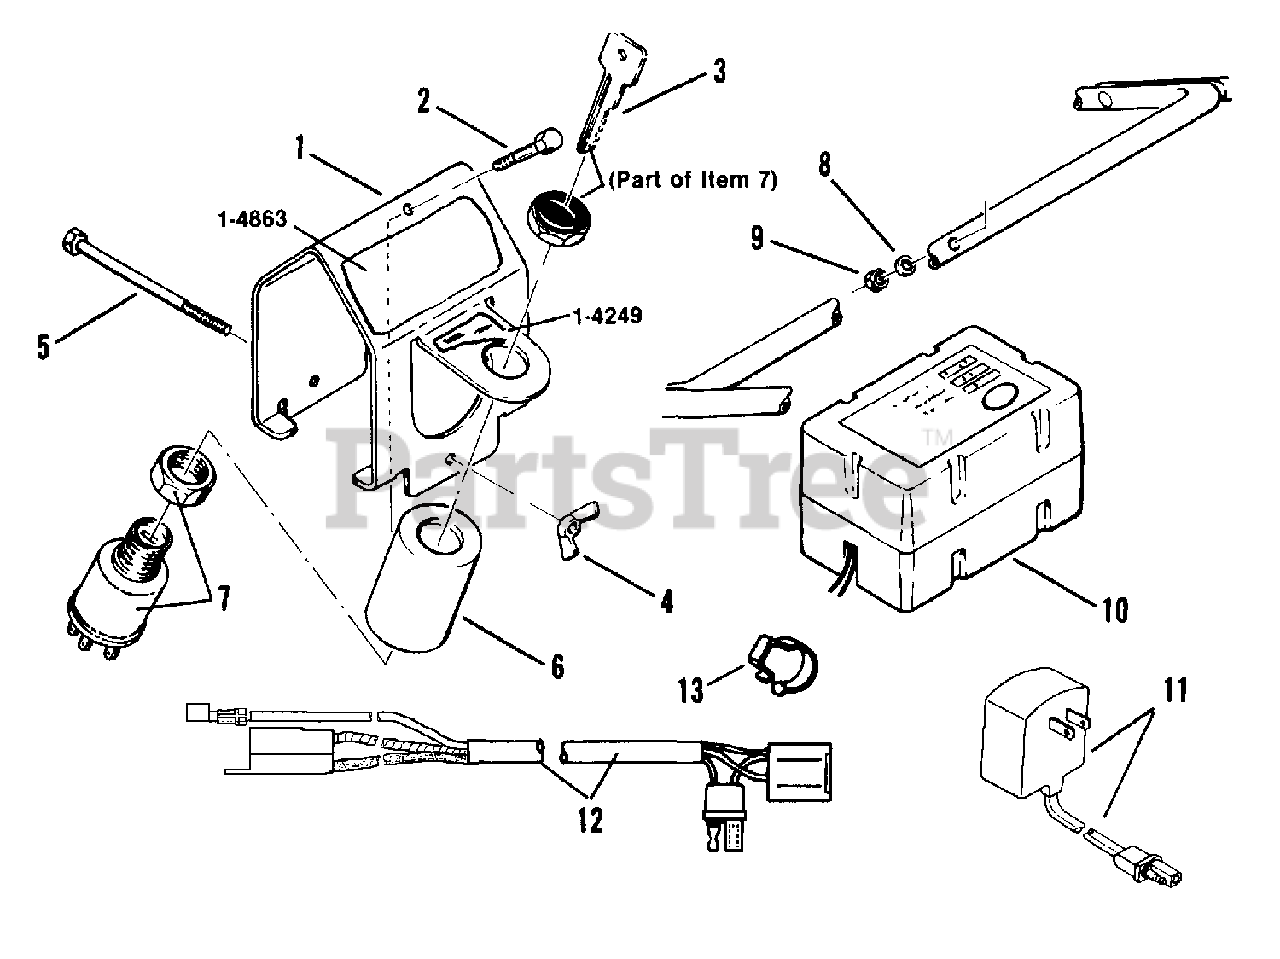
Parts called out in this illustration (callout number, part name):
1	BRACKET, Assembly (7037749 & 7014249)
2	CAPSCREW, 1/4F X 1-1/4
3	KEY, (Set of 2)
4	WING NUT 1/4F
5	CAPSCREW, 1/4F X 3-1/4
6	COVER, Switch
7	SWITCH, Ignition
8	LOCKWASHER, 1/4 Internal Tooth
9	NUT, 1/4F Hex
10	BATTERY KIT, 12 Volt
11	CHARGER, Battery (120V, 60 HERTZ)
11	CHARGER, Battery (240V, 50 HERTZ)
12	HARNESS, Wiring 52.05" (1982 Tec.)
13	CLIP, Wiring Harness
